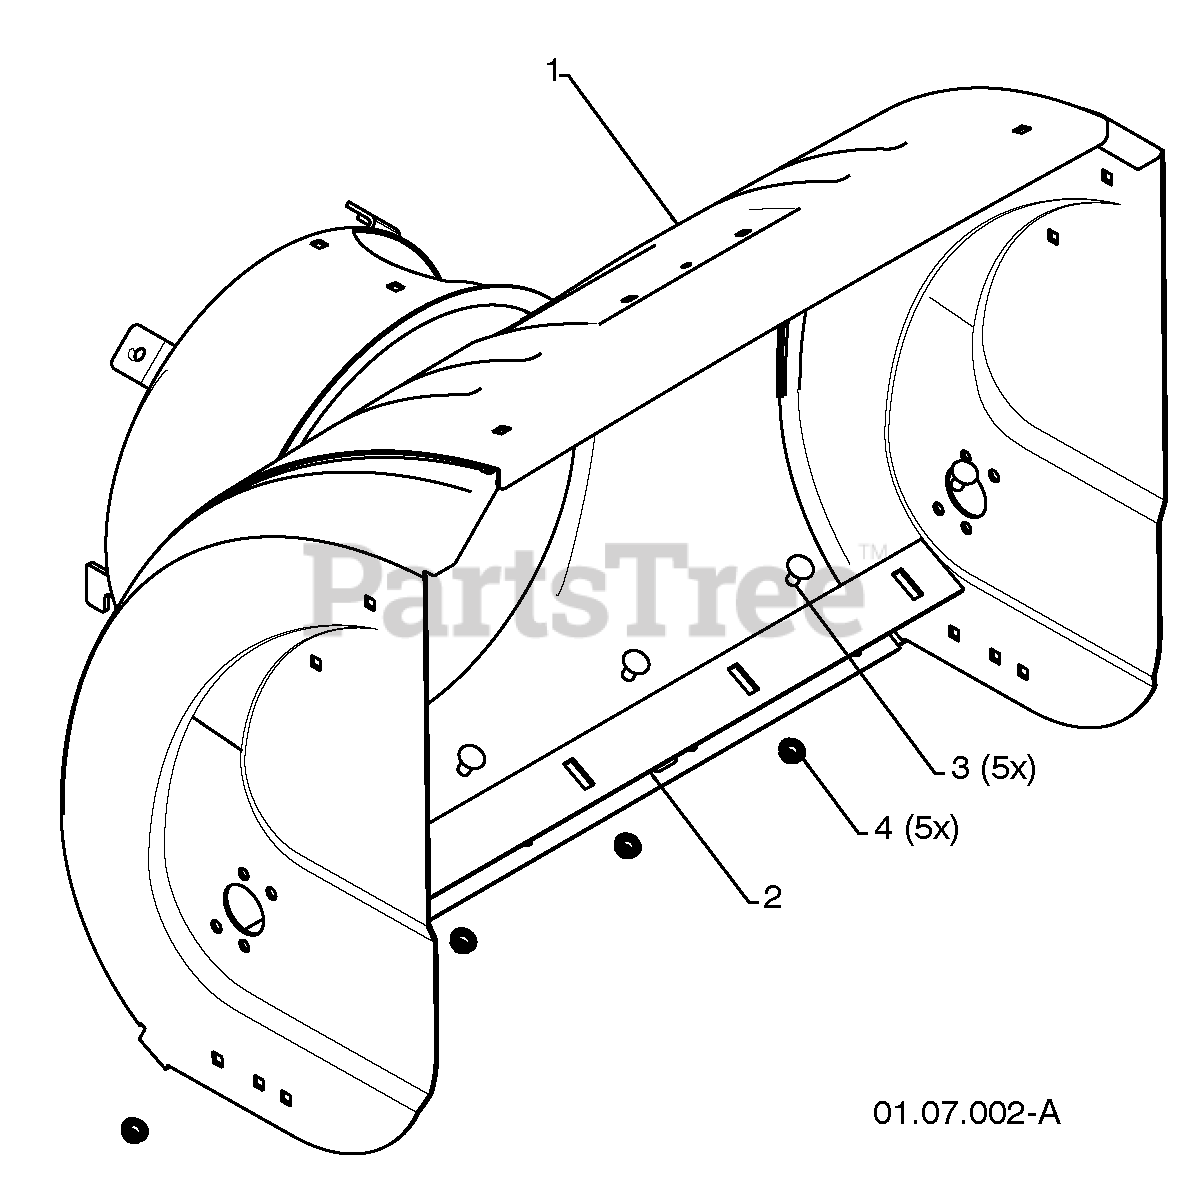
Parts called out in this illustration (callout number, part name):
1	AUGER HOUSING 27
2	SCRAPER BAR
3	CARRIAGE BOLT 5/16-18 X .625
4	NUT 5/16-18
